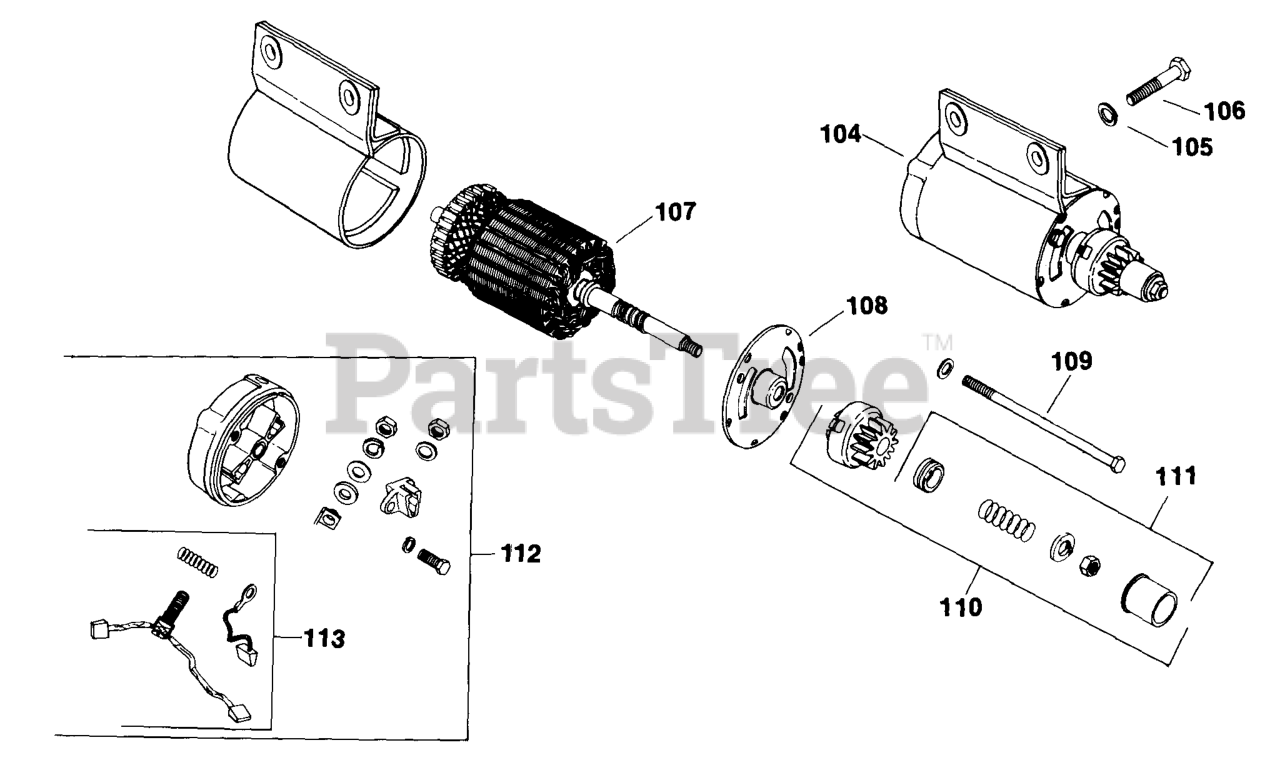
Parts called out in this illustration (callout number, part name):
104	STARTER - USE 41 098 07
105	WASHER, SPRING LOCK 3/8"
106	SCREW, CAP HD 3/8-16x1"
108	CAP - USE 45 081 05
111	DRIVE KIT - USE 41 755 34
112	CAP - DISCONTINUED
113	KIT - USE 52 755 15
